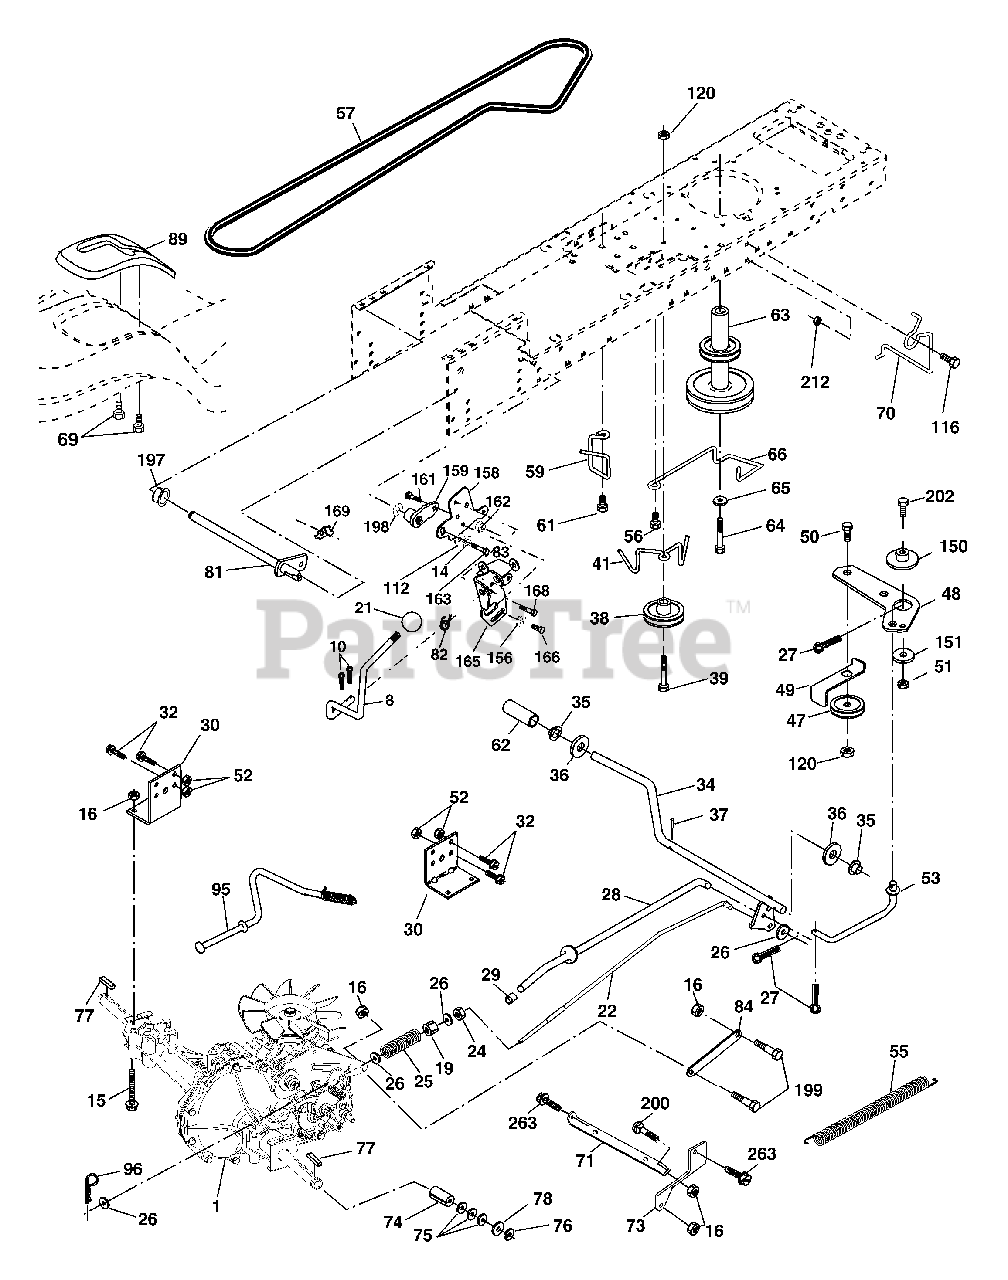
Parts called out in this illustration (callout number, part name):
8	Rod Shift Fender
10	Pin Cotter 1/8 x 1 CAD
14	Washer Lock Hvy Helical 1/4
15	Bolt Hex Flg Hd 5/16-18 x Gr.5
16	Nut Lock Hex W/Ins. 5/16-18 unc
19	Nut Lock Hex W/Wsh 3/8-16 unc
21	Knob, Deluxe
22	Rod, Brake Hydro
24	Nut
25	Spring, Brake Rod
26	Washer
27	Pin Cotter 1/8 x 3/4 CAD.
28	Rod, Parking Brake
29	Cap, Parking Brake
30	Bracket, Transaxle
32	Bolt Hex Hd 5/16-18 unc x 3/4
34	Shaft, Foot Pedal
35	Bearing, Nylon
37	Pin, Roll
38	Pulley, Composite
41	Keeper, Belt Idler
47	Pulley, Idler, V-Groove
48	Bellcrank Clutch Grnd Drv Stl
49	Retainer, Belt
52	Nut Crownlock 5/16-18
53	Link, Clutch
55	Spring, Return, Clutch
56	Screw 3/8-16 x 1-1/4
57	V-Belt, Ground Drive
59	Keeper, Center Span
61	Screw 3/8-16 x .875
62	Cover, Pedal
63	Pulley, Clutch Eng
64	Bolt Hex 7/16-20 x 4 Ga. 5
65	Washer
66	Keeper Belt Engine
69	Screw Hex Wsh Hi-Lo 1/4-1/2 unc
70	Guide Belt Mower Drive RH
71	Strap Torque Lh Hydro
73	Strap Torque Rh Hydro
74	Spacer, Axle
75	Washer 25/32 x 1-1/4 x 16 Ga.
77	Key, Square
78	Washer 25/32 x 1-5/8 x 16 Ga.
81	Shaft Asm. Cross Hydro
82	Spring Torsion T/A
83	Washer 17/32 x 3/4 x 16 Ga.
84	Link Transaxle
89	Console, Shift
95	Control Asm Bypass Hydro
96	Retainer Spring 1" Zinc/Cad
112	Washer 9/32 x 3/4 x 10 Ga.
116	Boulon 3/8-16 x 1
120	Nut Lock Flg 3/8-16
150	Spacer Retainer
151	Washer 13/32 x 2 x 10 Ga.
156	Washer Srrtd 5/16 ID x 1.0 x .125 Tk
158	Bracket Shift Mount
159	Hub Shift
161	Bolt Rdhd Sqnk 1/4-20 x 3/4 Gr. 5
162	Nut Crownlock 1/4-20 unc
163	Bolt Hex Fin 1/4-20 unc x 1 Gr. 5
165	Bracket Pivot Lever
166	Screw 5/16-18 x 5/8 TT Yellow
168	Bolt Shoulder 5/16-18 x .561 TT
169	Plate Fastening Cross Shf. STLT/CRD
197	Nyliner Snap-In 5/8" ID
198	Washer Nyl. 7/8 ID x .105"
199	Bolt Shoulder 5/16-18 unc
200	Bolt Rdhd Sq Neck 5/16-18 unc x 1
202	Bolt Carr Sh 3/8-16 x 1-3/4 Gr. 5
212	Nut Hex Flg Lock
263	Screw 3/8-16 x 3/4
